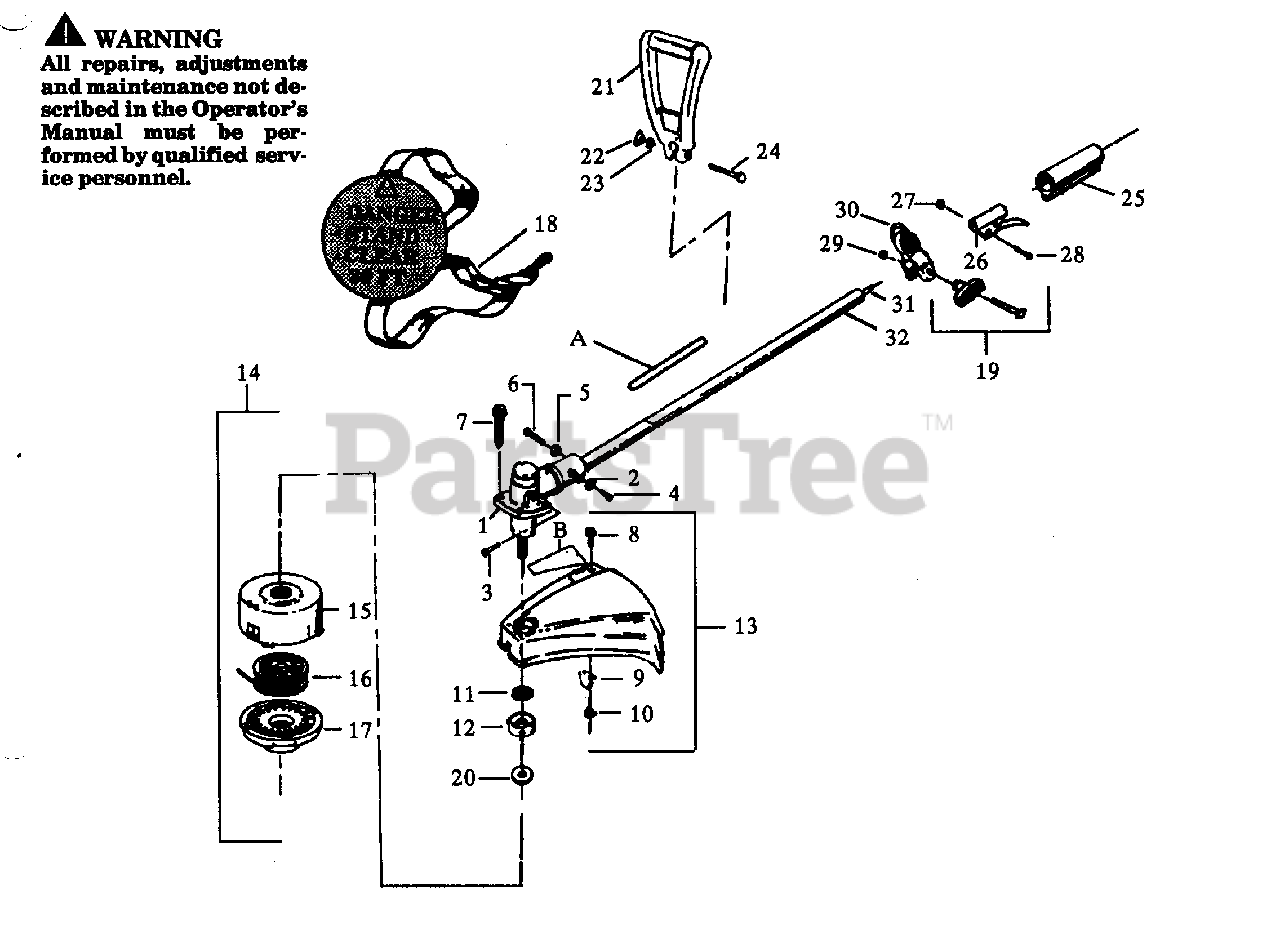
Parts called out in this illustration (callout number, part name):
1	Gear Box Ass'y.
2	Lockwasher
5	Lockwasher
7	Screw
9	Line Limiter
10	Locknut
12	Dust Cup
13	Shield Kit Ass'y.
14	Cutting Hd. Ass'y. (Inc.15, 16 & 17)
15	Hub Ass'y.
16	Spool w/Line
18	Shoulder Strap
19	"T" Handle Kit
21	Assist Handle
22	Wing Nut
26	Throttle Lever Ass'y.
27	Lock Nut
30	Clamp Harness Ass'y.
31	Drive Shaft
32	Drive Shaft Hsg. (Inc.31)
B	Shield Warning Decal
